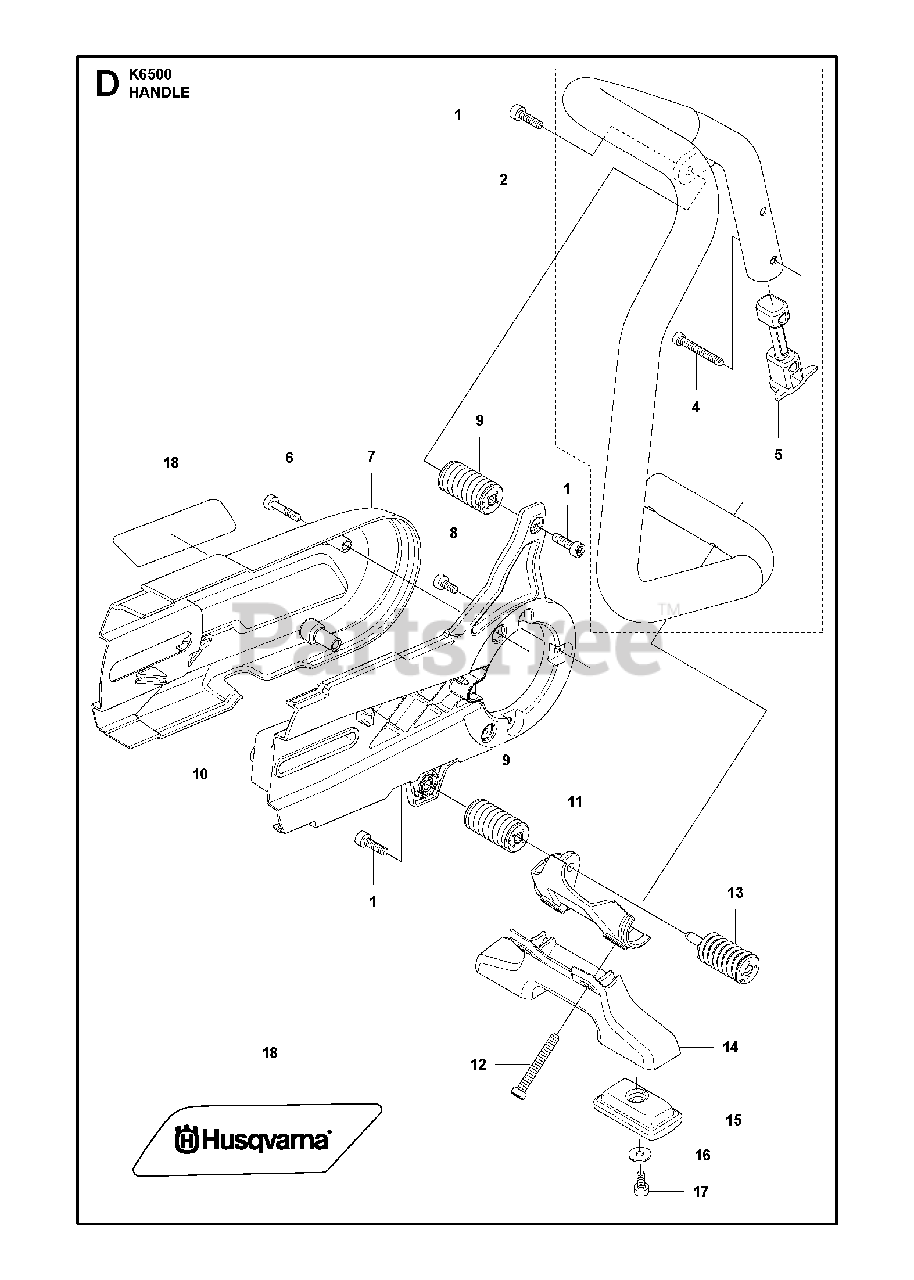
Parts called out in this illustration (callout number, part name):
1	SCREW ITXSCM
2	FRONT HANDLE ASSYInkl. 3-5
6	SCREW ITXSCM
8	SCREW ITXSCM
9	ANTIVIBRATION ELEMENT
12	SCREW ITXSCT
13	ANTIVIBRATION ELEMENT
17	SCREW ITXSCM
